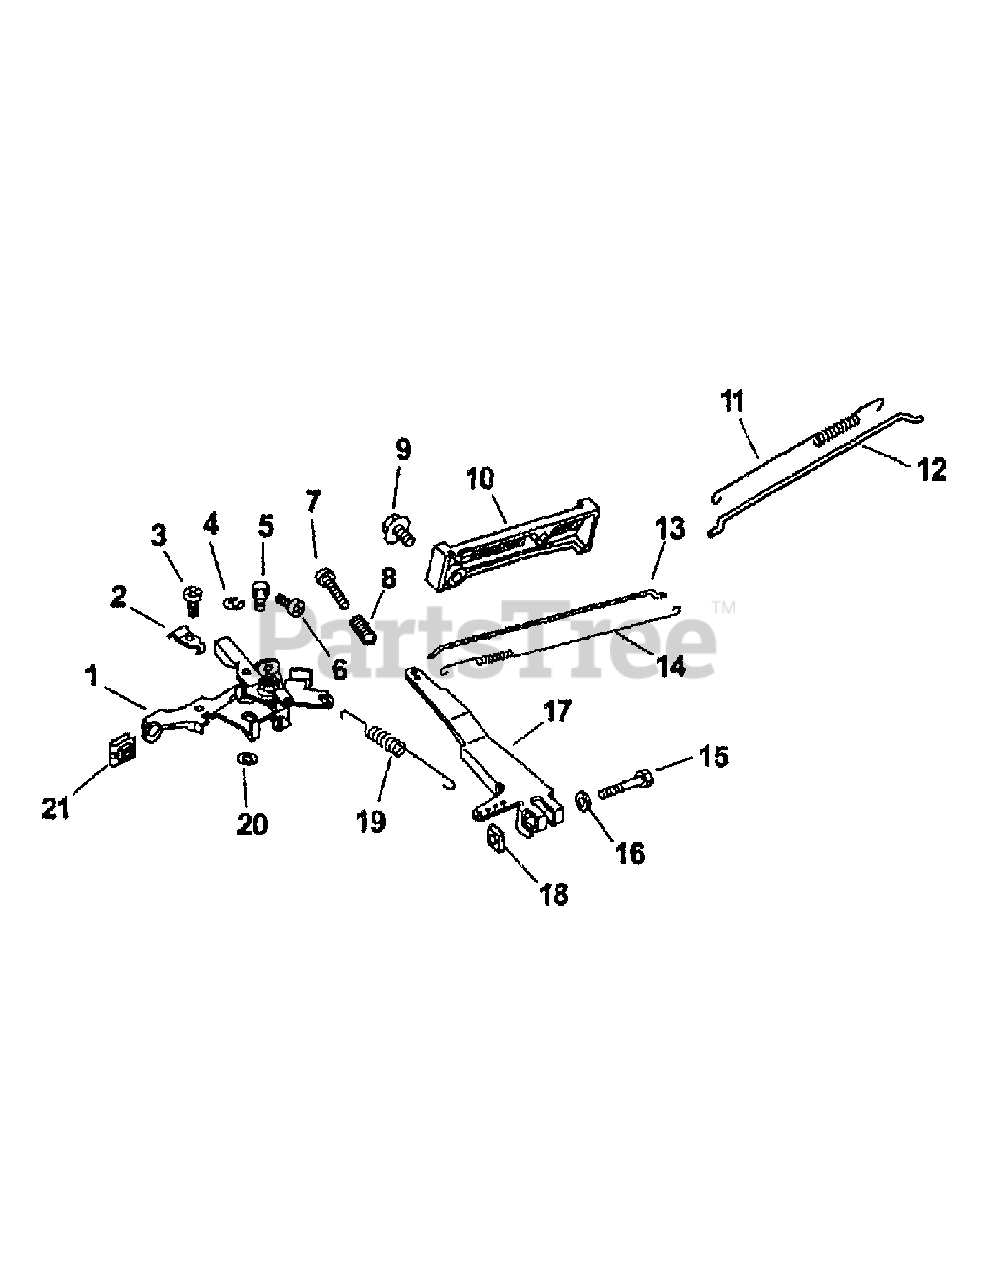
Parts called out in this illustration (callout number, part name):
1	Assembly, Throttle
2	Clamp, Bowden
5	Clamp, Wire
7	Screw, Pan Head
8	Spring, Compression
10	Panel, Speed & Choke
11	Spring, Choke
13	Link, Throttle
14	Spring, Linkage
17	Lever, Governor
19	Spring, Governor
